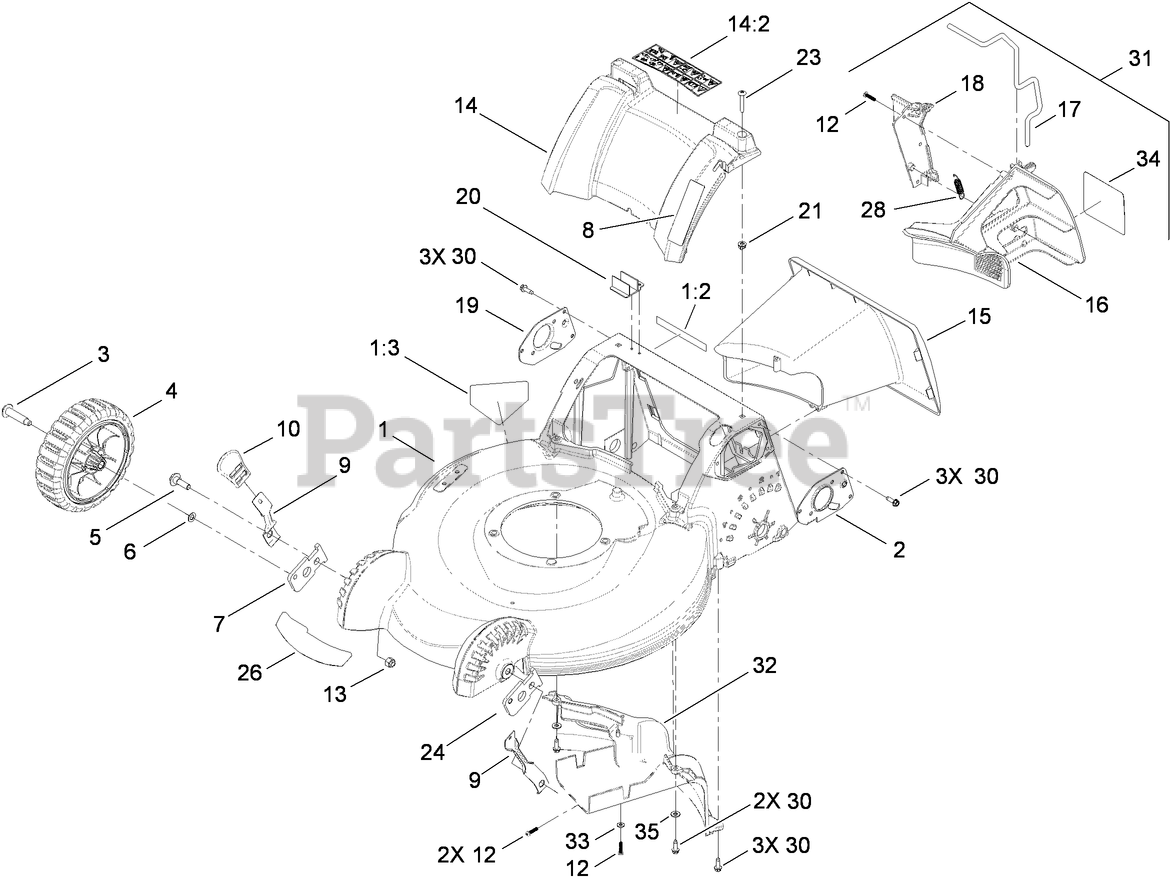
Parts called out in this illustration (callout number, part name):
1	HOUSING ASM
1:3	DECAL-DANGER
2	MOUNT-HANDLE, LH
3	BOLT-SHOULDER
4	8 INCH WHEEL ASM
5	SCREW-SHOULDER, HWH
6	WASHER
7	ARM-PIVOT, RH
8	DECAL-QUICK STOW
9	ARM-SPRING, FRONT
10	KNOB-HOC
12	SCREW-PLASTITE
13	NUT-LOCK, NI
14	REAR COVER ASM
14:2	DECAL-WARNING
15	TUNNEL
16	PLUG-MULCH, LH
17	LATCH-PLUG, MULCH
18	PLUG-MULCH, RH
19	MOUNT-HANDLE, RH
20	MODULE-SWITCH
21	NUT-CLIP
23	SCREW-PTH
24	ARM-PIVOT, LH
26	DECAL-SUPER BAGGER
28	SPRING-EXTENSION
30	SCREW-HWHTF
31	MULCH PLUG ASM
32	BAFFLE-REAR
33	WASHER-FLAT
34	DECAL-PLUG, MULCH
35	WASHER-FLAT
